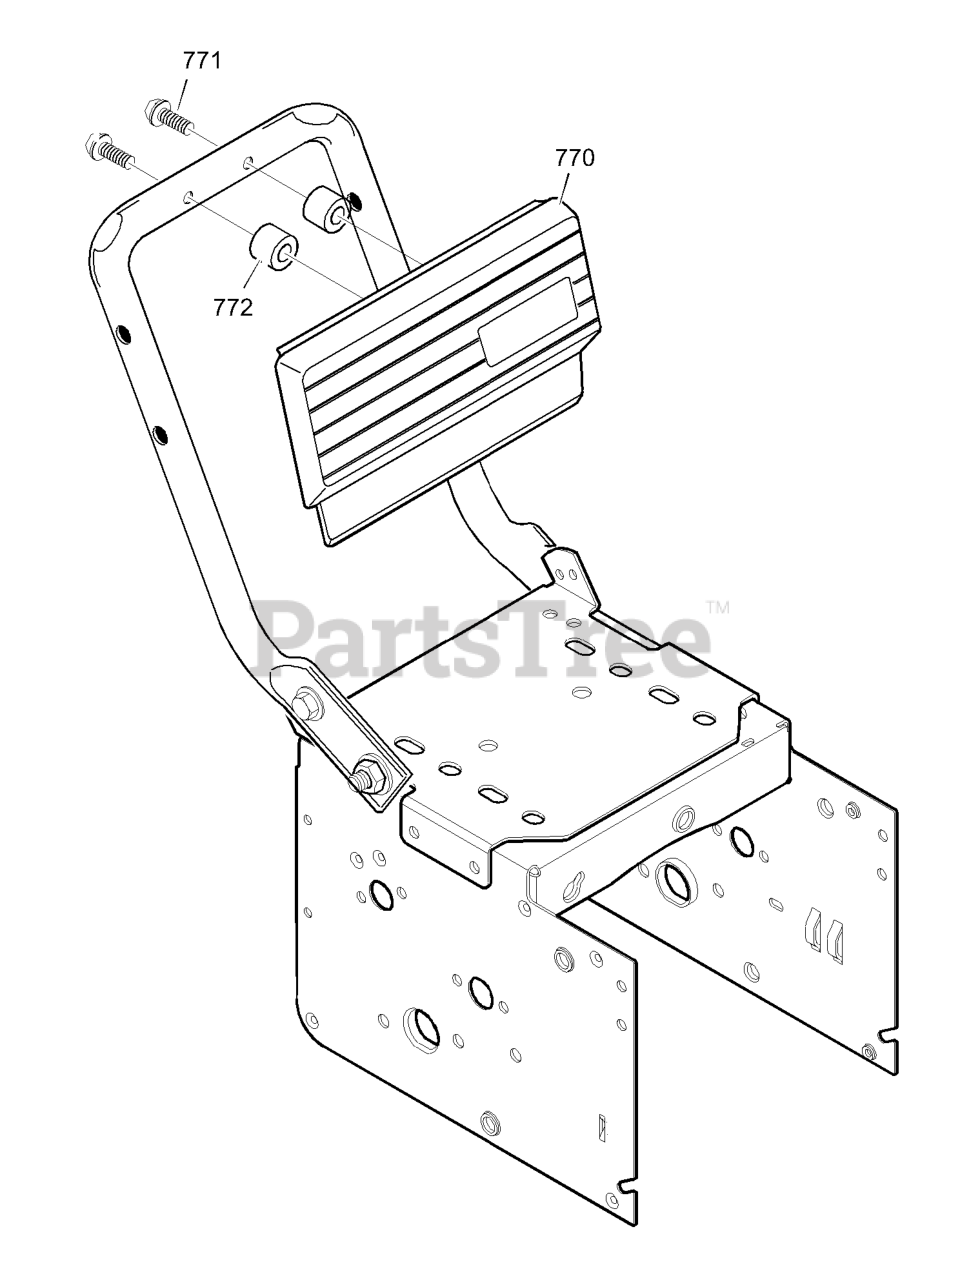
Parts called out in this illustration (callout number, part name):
770	PANEL, DECO -BLACK
771	SCREW, #10 -12 x 1.50
772	SPACER, SLEEVE
